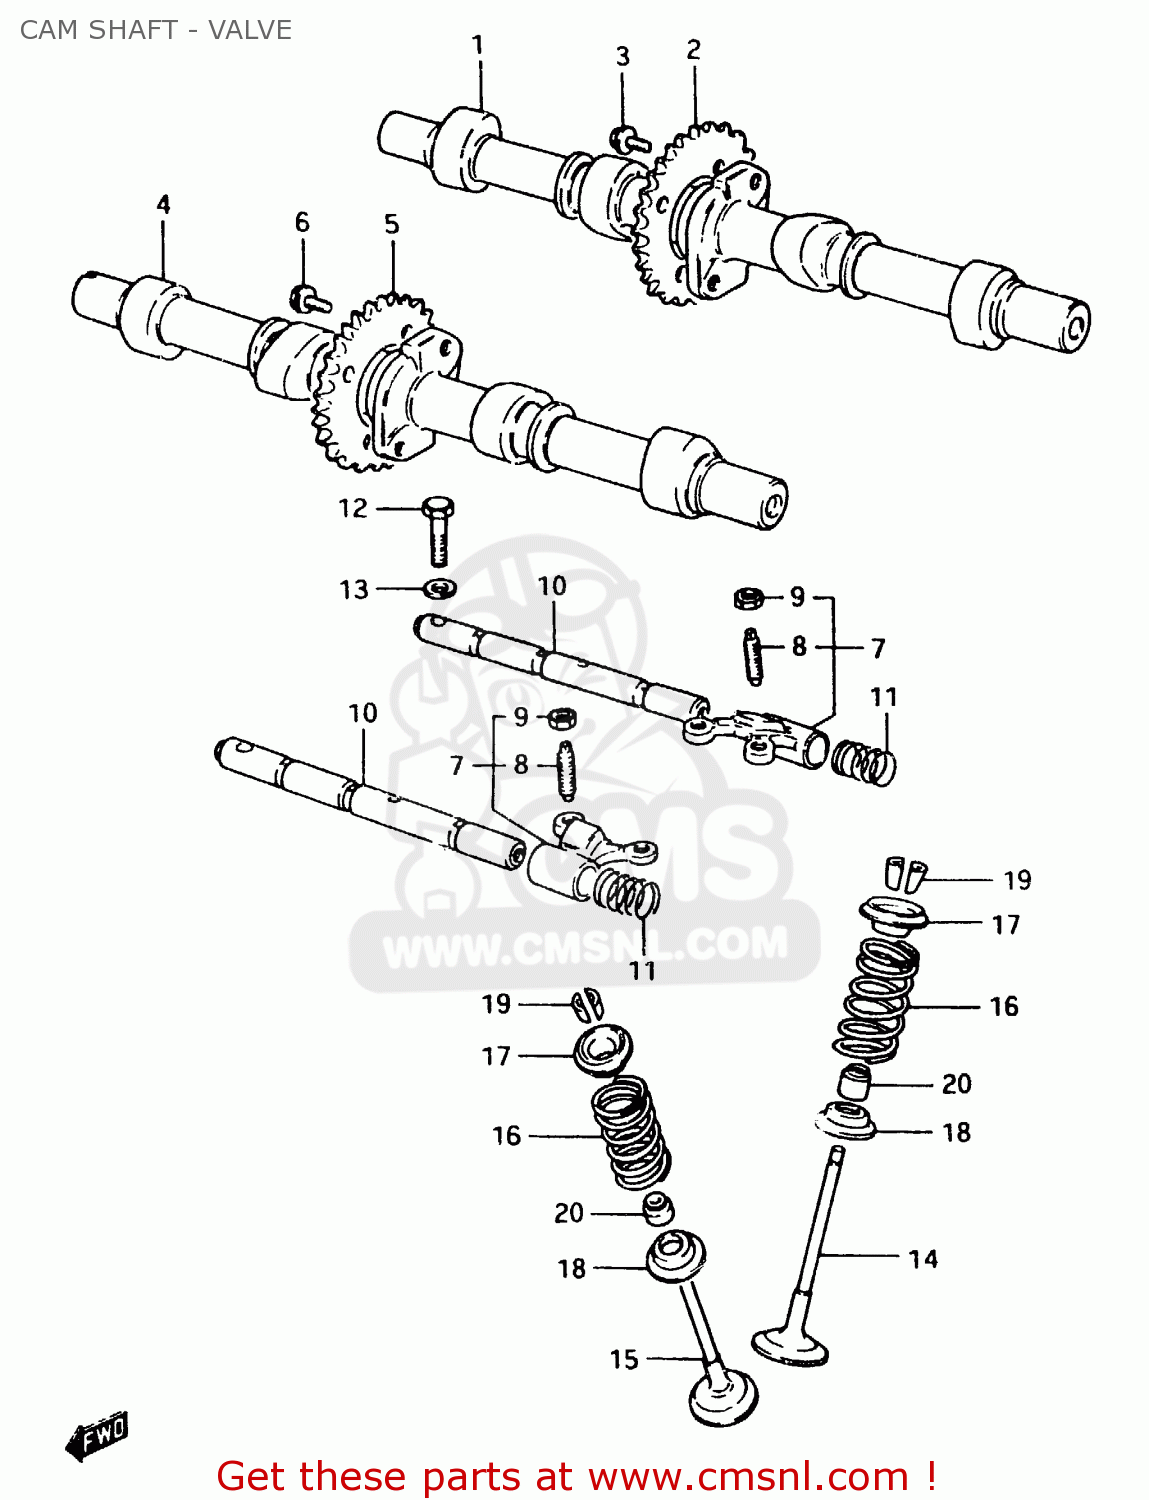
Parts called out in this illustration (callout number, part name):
1	CAMSHAFT,INTAKE
2	SPROCKET,INTAKE CAMSHAFT
3	BOLT(7X11)
4	CAMSHAFT,EXHAUST
5	SPROCKET,EXHAUST CAMSHAFT
6	BOLT(7X11)
7	ARM,VALVE ROCKER
8	SCREW,TAPPET ADJUSTING
9	NUT,ADJUSTING
10	SHAFT,VALVE ROCKER
11	SPRING
12	BOLT
13	WASHER
14	VALVE,INTAKE
15	VALVE,EXHAUST
16	SPRING,VALVE
17	RETAINER,VALVE SPRING
18	SEAT,VALVE SPRING
19	COTTER VALVE
20	OIL SEAL
